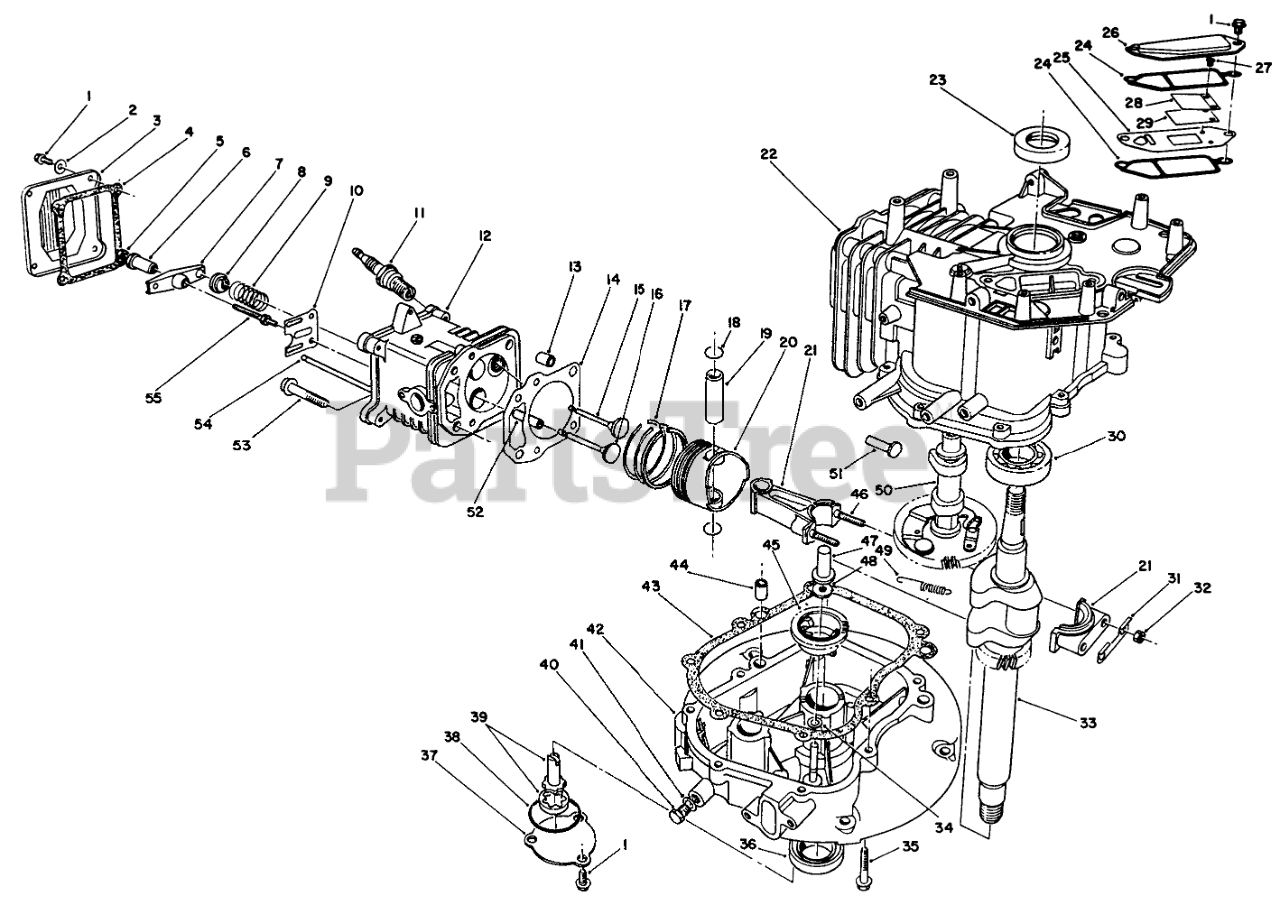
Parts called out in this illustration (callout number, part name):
2	WASHER
3	COVER
4	GASKET
6	PIVOT
8	RETAINER
9	SPRING
10	GUIDE
11	SPARK PLUG
12	Head-Cylinder(Incl. Ref. #52)
14	GASKET
15	VALVE-EXHAUST
16	VALVE-INTAKE
17	RING SET
18	CIRCLIP
20	PISTON
21	Connecting Rod Assembly (Incl. Ref. #31, 32 & 46)
22	Block-Engine (Incl. Ref. #23 & 30)
24	GASKET
25	Plate-Breather
26	COVER
27	Screw-Reed Valve
28	Retainer-Reed Valve
29	Valve-Reed
30	BEARING
31	Plate-Lock
33	CRANKSHAFT
34	WASHER
37	COVER
38	O-RING
39	OIL PUMP
40	OIL DRAIN PLUG
41	GASKET
42	Crankcase
43	GASKET
45	GOVERNOR FLYWEIGHT ASM
47	PLUNGER
48	WASHER
49	SPRING
50	Camshaft Assembly (Incl. Ref. #49)
51	TAPPET
52	GUIDE
